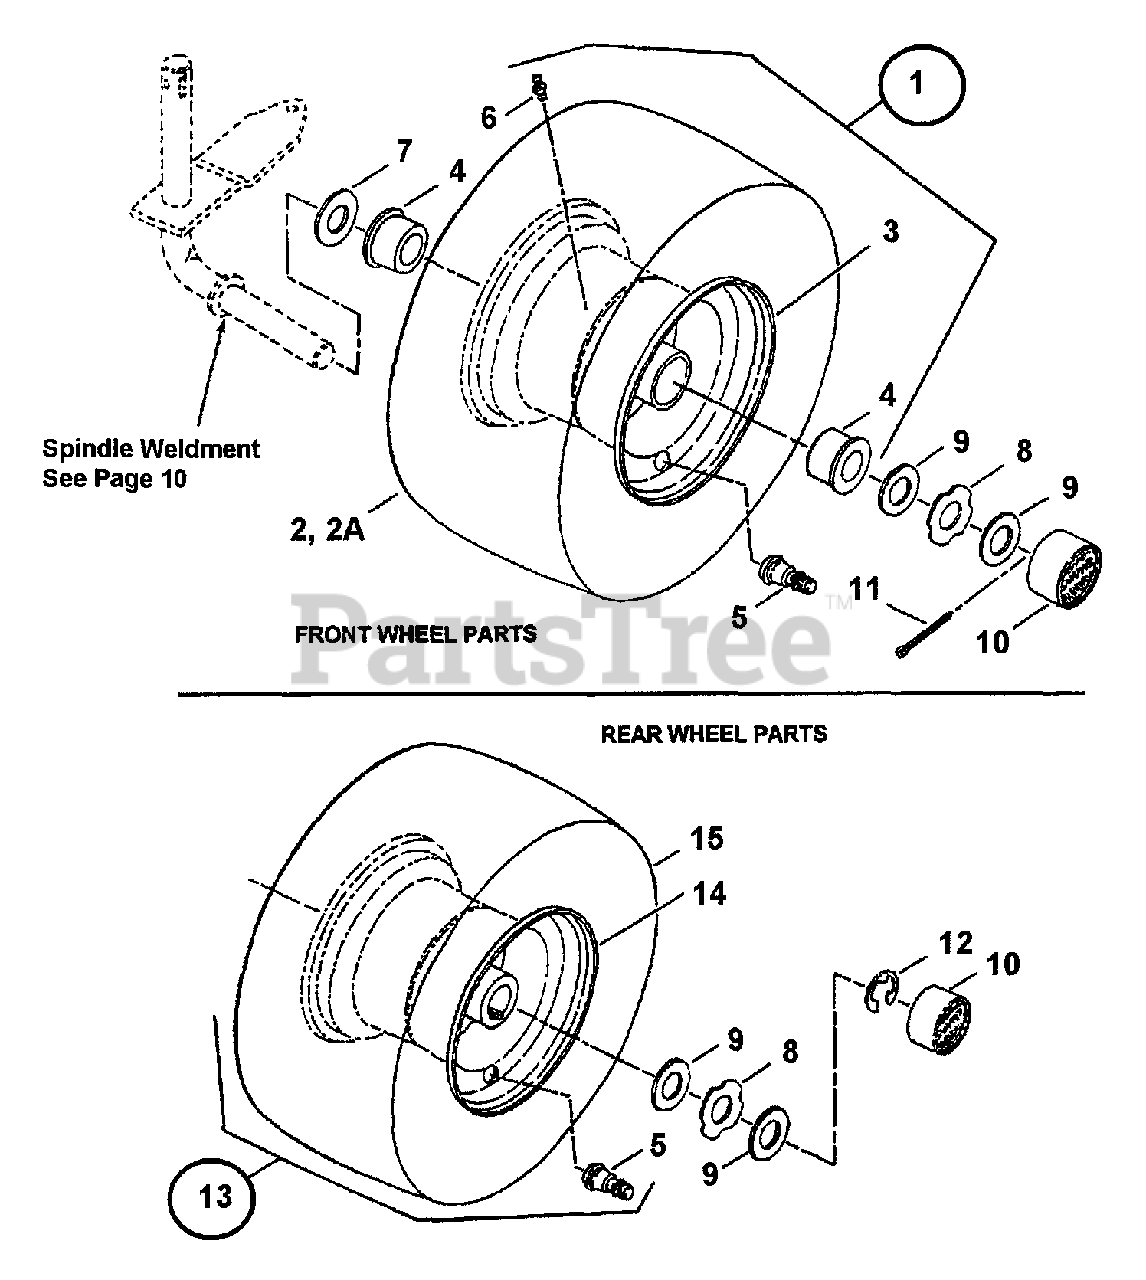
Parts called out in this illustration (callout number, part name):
1	ASSEMBLY, Front Tire & Rim
2	TIRE, 13 x 5.00
2A	TIRE, 15 x 6.00
3	RIM, 6.00 x 3.50
4	BEARING, Wheel
5	VALVE, Air (Snap-in)
6	FITTING, Lube 1/4-28 Tapered Thread
7	WASHER, Flat, 5/32 x 25/32" I.D. x 1-1/2" O.D.
8	WASHER, Hub-Cap Retaining
9	WASHER, Flat, 1/16 x 49/64 I.D. x 1-5/16" O.D.
10	HUB-CAP
11	COTTER-PIN, 5/32 x 1"
12	RING, External Retaining, 3/4"
13	ASSEMBLY, Rear Tire & Rim
14	RIM, 8 x 7.00
15	TIRE, 18 x 8.50-8
